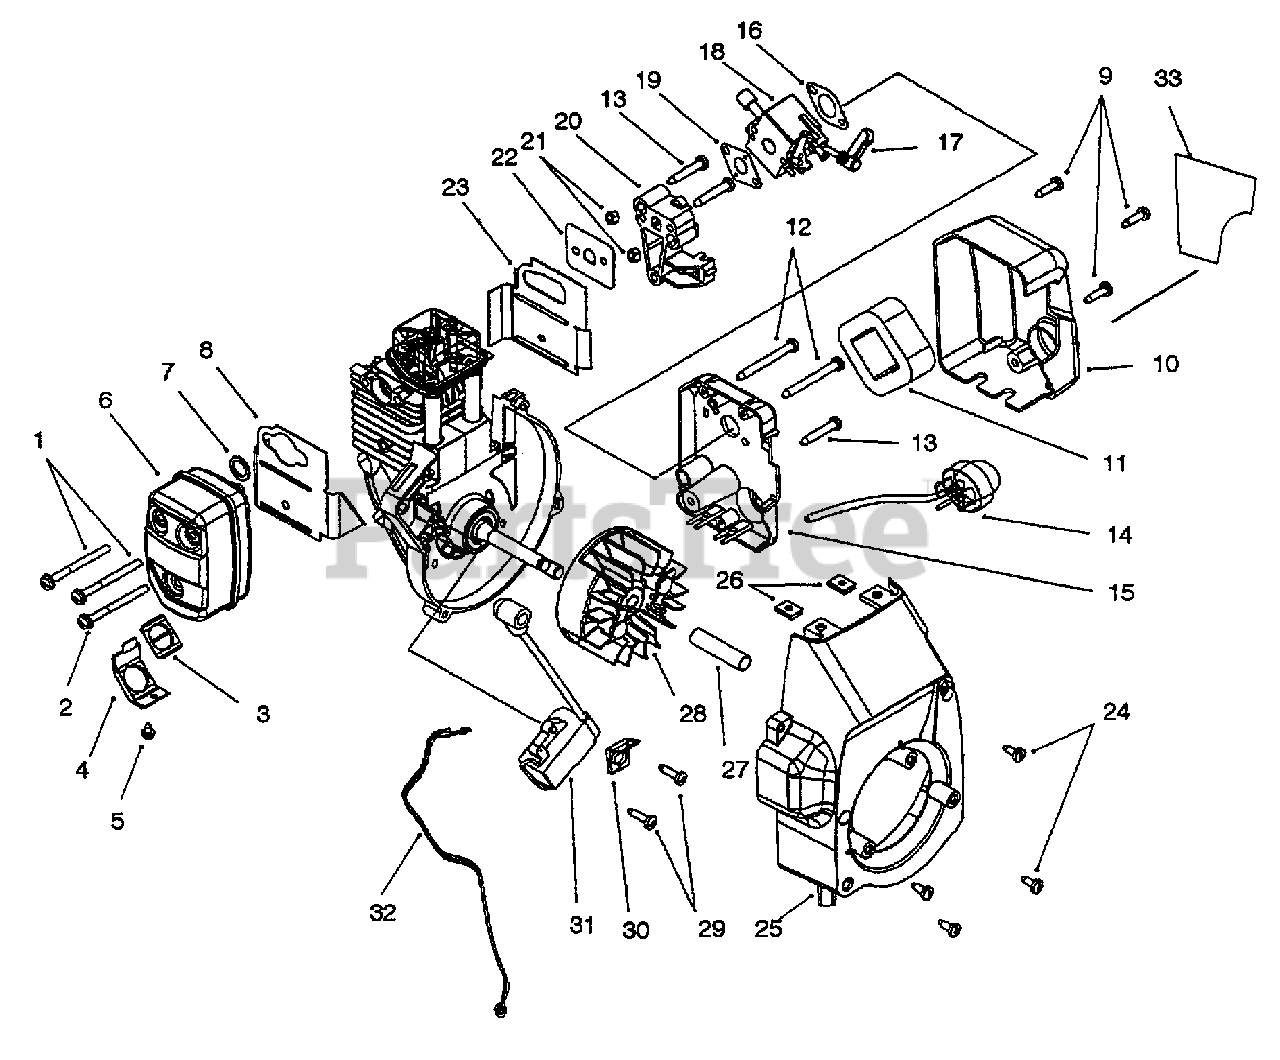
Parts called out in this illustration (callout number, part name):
1	Screw-Muffler Mounting
2	Screw-Muffler Mounting
3	Screen-Spark Arrestor
4	Cover-Screen
5	Screw-Screen Cover
6	Muffler (Incl. Ref. #1-5 & 7)
7	Gasket-Muffler
8	Baffle-Muffler
9	Screw-Air Filter Cover
10	Cover-Air Filter
11	Filter-Air
12	Screw-Air Filter Base
14	Primer & Line Assembly
15	Base-Air Filter
17	Lever-Choke
18	Carburetor W/Choke Lever
20	Insulator-Carb. Mount
21	Nut-Hex
22	Gasket-Intake
23	Baffle-Intake
25	Housing-Fan
26	Nut-Tinnerman
28	Flywheel
29	Screw-Module
30	Tab-Ground
31	Module-Ignition
32	Lead-Wire 18"
33	Decal-Choke
